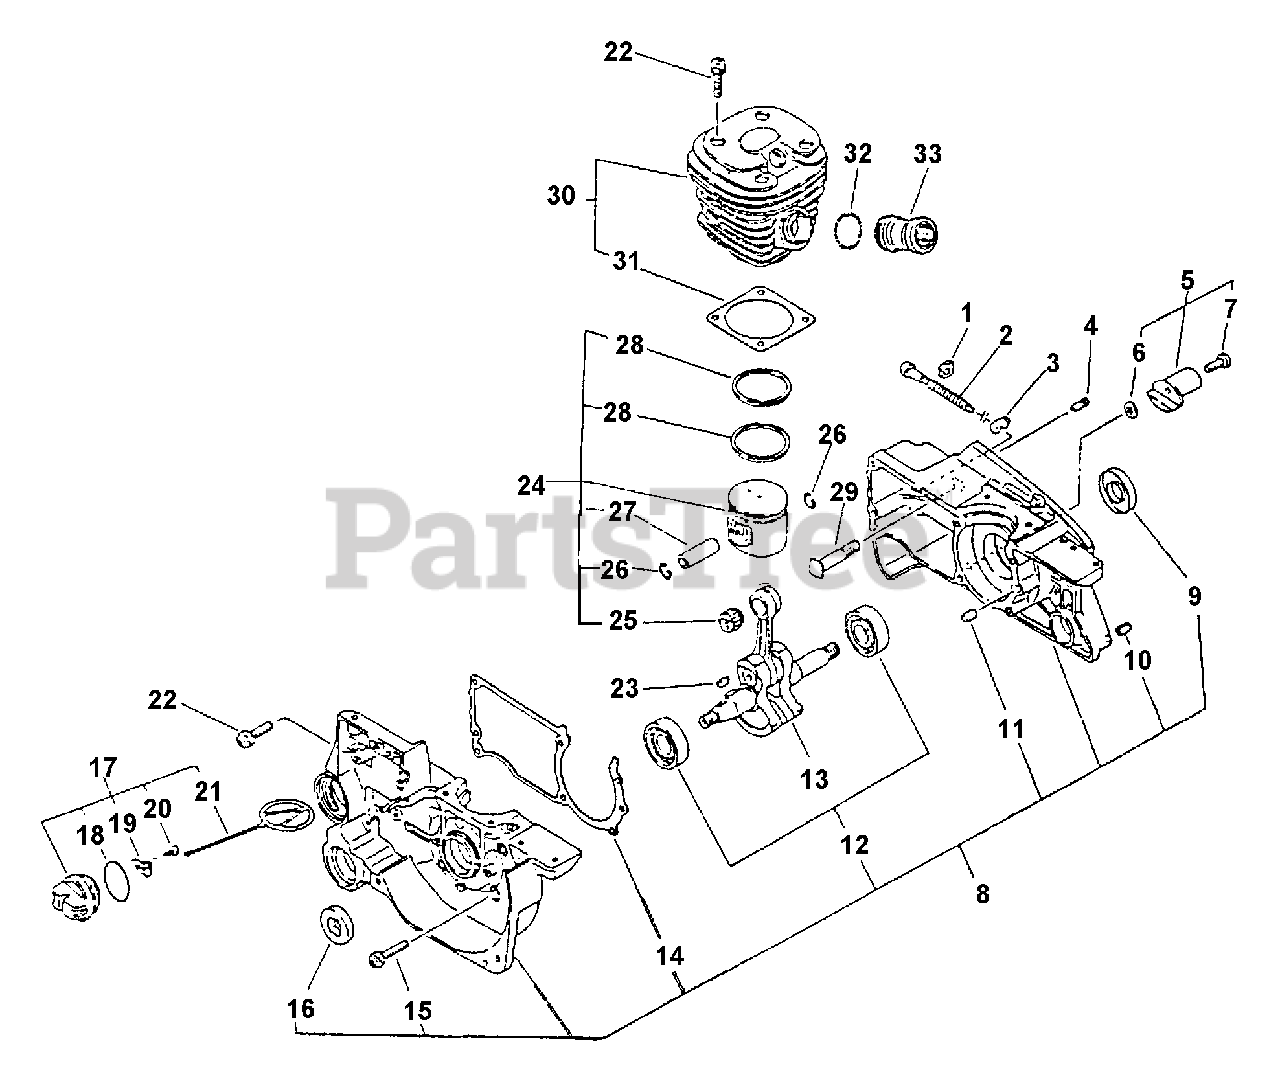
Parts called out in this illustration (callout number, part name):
2	SCREW, TENSIONER
3	TENSIONER, CHAIN
4	VENT, TANK
5	CHAIN CATCHER KIT
6	WASHER - 5
7	SCREW - 5X18
8	CRANKCASE KIT
9	SEAL, OIL
10	PIN - SPRING -- 5X10
11	PIN - LOCATING
12	BEARING, BALL - 6202
13	CRANKSHAFT ASSY
14	GASKET, CRANKCASE
15	SCREW - 5X30
16	SEAL, OIL
17	CAP ASSY
18	O-RING - 25
19	RETAINER
20	SCREW - 3X8
21	CONNECTOR, CAP
22	SCREW - 5X20
24	PISTON KIT
25	BEARING, NEEDLE
26	RING, RETAINING - 8
27	PIN, PISTON
28	RING, PISTON
29	STUD, GUIDE BAR
30	CYLINDER KIT
31	GASKET, CYLINDER
32	BAND
33	ADAPTOR, INTAKE
